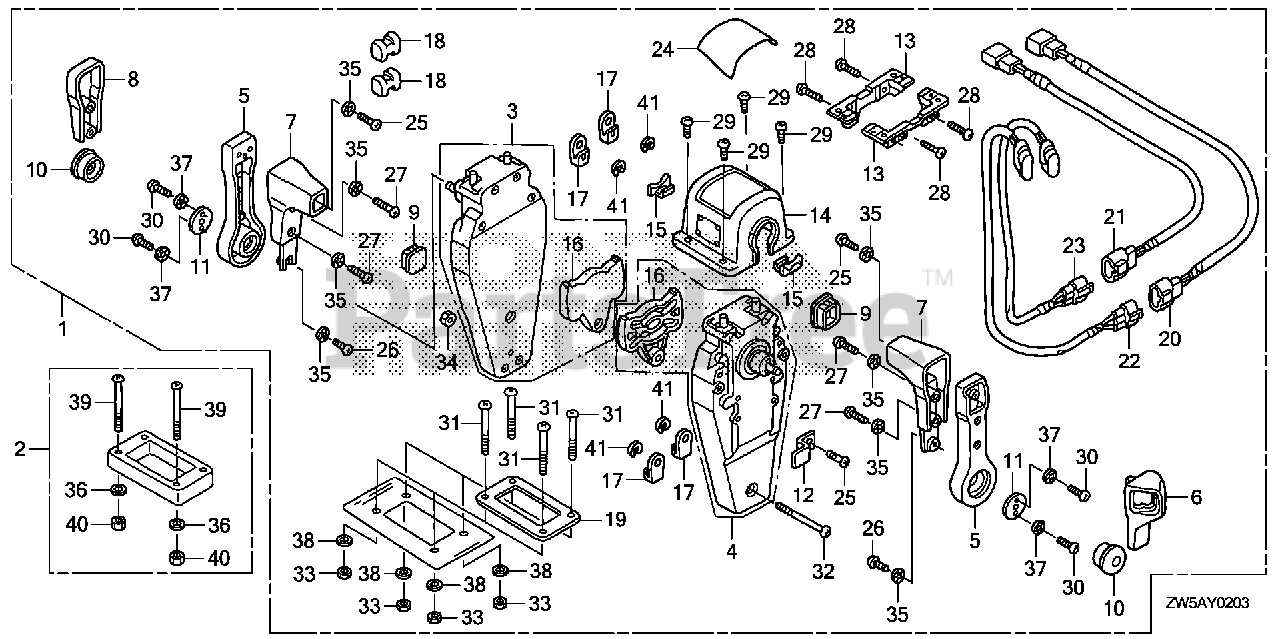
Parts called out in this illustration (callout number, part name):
1	BOX KIT, REMOTE CONTROL (TOP MOUNT DUAL)(L)
2	SPACER KIT, REMOTE CONTROL BOX (TOP MOUNT DUAL)
3	HOUSING ASSY., L. (INNER) (TOP MOUNT)
4	HOUSING ASSY., R. (INNER) (TOP MOUNT)
5	HANDLE, REMOTE CONTROL
6	COVER, R. GRIP
7	GRIP, REMOTE CONTROL HANDLE
8	COVER, DUAL GRIP
9	CAP, GRIP
10	BUTTON, THROTTLE
11	PLATE, HANDLE
12	PLATE, CABLE CLAMP
13	BRACKET, REMOTE CONTROL HOUSING
14	HOUSING, DUAL REMOTE CONTROL BOX
15	HOUSING, LEAD
16	PLATE, DWELL
17	TERMINAL, CABLE
18	SPACER, CABLE CLAMP
19	GASKET, DUAL
20	SUB-HARNESS ASSY., POWER TRIM-TILT (A)
21	SUB-HARNESS ASSY., POWER TRIM-TILT (B)
22	SWITCH ASSY., POWER TRIM-TILT (A)
23	SWITCH ASSY., POWER TRIM-TILT (B)
24	MARK, REMOTE CONTROL (DUAL)
25	SCREW, PAN (5X16)
26	SCREW, PAN (5X10)
27	SCREW, PAN (5X20)
28	SCREW, PAN (5X18)
29	SCREW, PAN (4X10)
30	SCREW, PAN (6X18)
31	SCREW, PAN (5X40)
32	SCREW, PAN (5X55)
33	NUT, HEX. (5MM)
34	NUT, HEX. (5MM)
35	WASHER, LOCK (5MM)
36	WASHER, PLAIN (5MM)
37	WASHER, LOCK (6MM)
38	WASHER, PLAIN (5MM)
39	SCREW, PAN (5X65)
40	NUT, HEX. (5MM)
41	E-RING (6MM)
